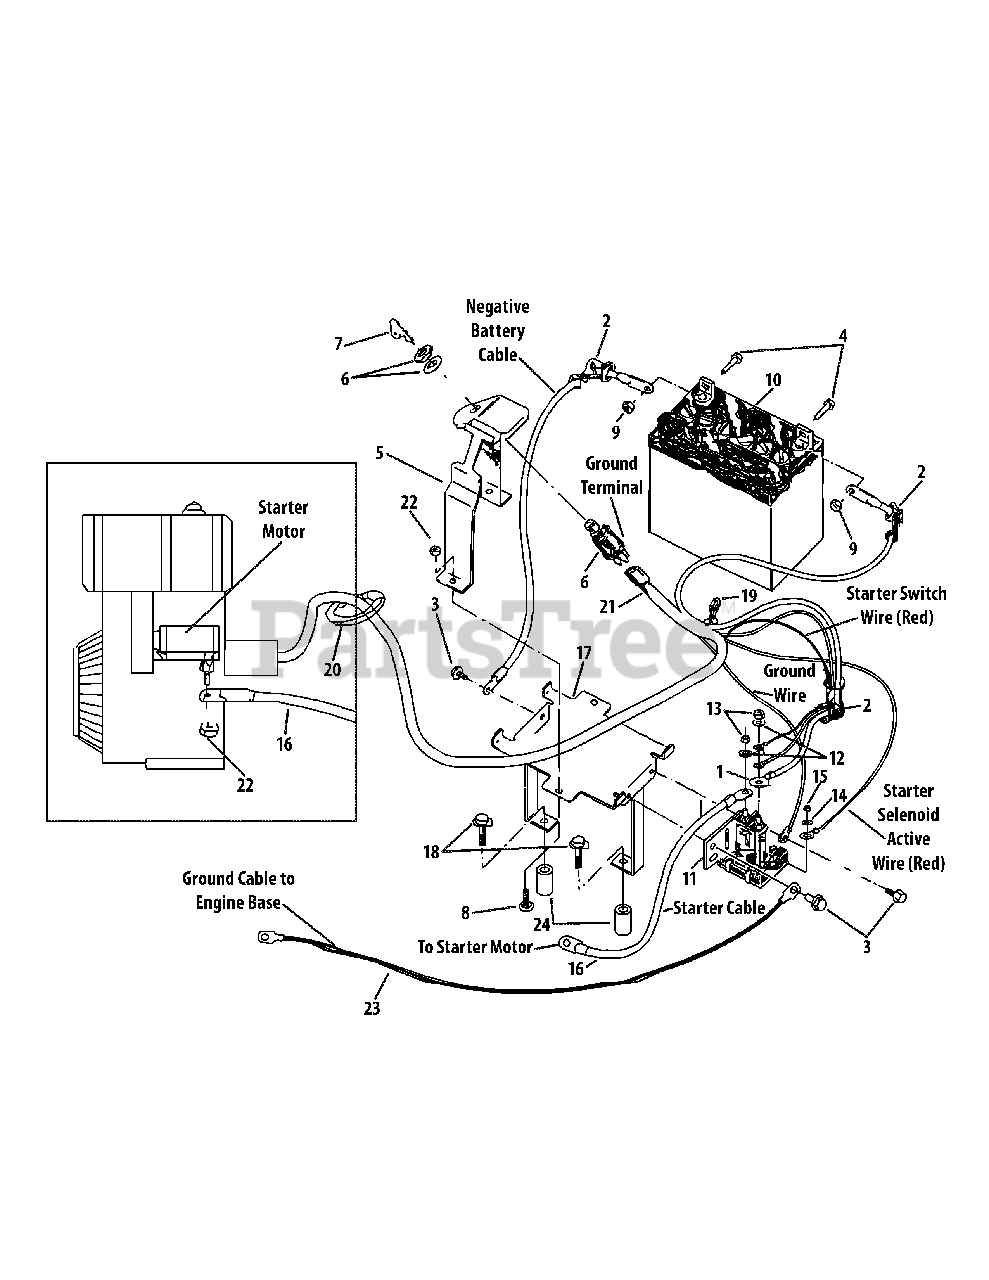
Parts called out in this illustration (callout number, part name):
1	Battery Cable
2	Terminal Insulating Boot
3	TT-Screw, 1/4-2 x 1/2"
4	Hex Bolt, 1/4-20 x 5/8 "
5	Battery Hold-down Clamp w/ Att. Key Switch Plate
6	Key Switch
7	Ignition Key
8	Carriage Bolt, 1/4-20 x 1-1/4"
9	Hex Nut, 1/4"-20
10	12-Volt Battery
11	Starter Solenoid
12	Lockwasher,5/16"
13	Hex Nut, 5/16 "-24
14	External Tooth Lockwasher
15	Hex Nut, #10-32
16	Solenoid Cable
17	Battery Bracket
18	HH Cap Screw, 3/8 -16 x 2.75"
19	Plastic Tie
20	Plastic Tie
21	Wire Harness & Connecting Terminal Assembly
22	Hex Locknut, 1/4"-20
23	Ground Cable
